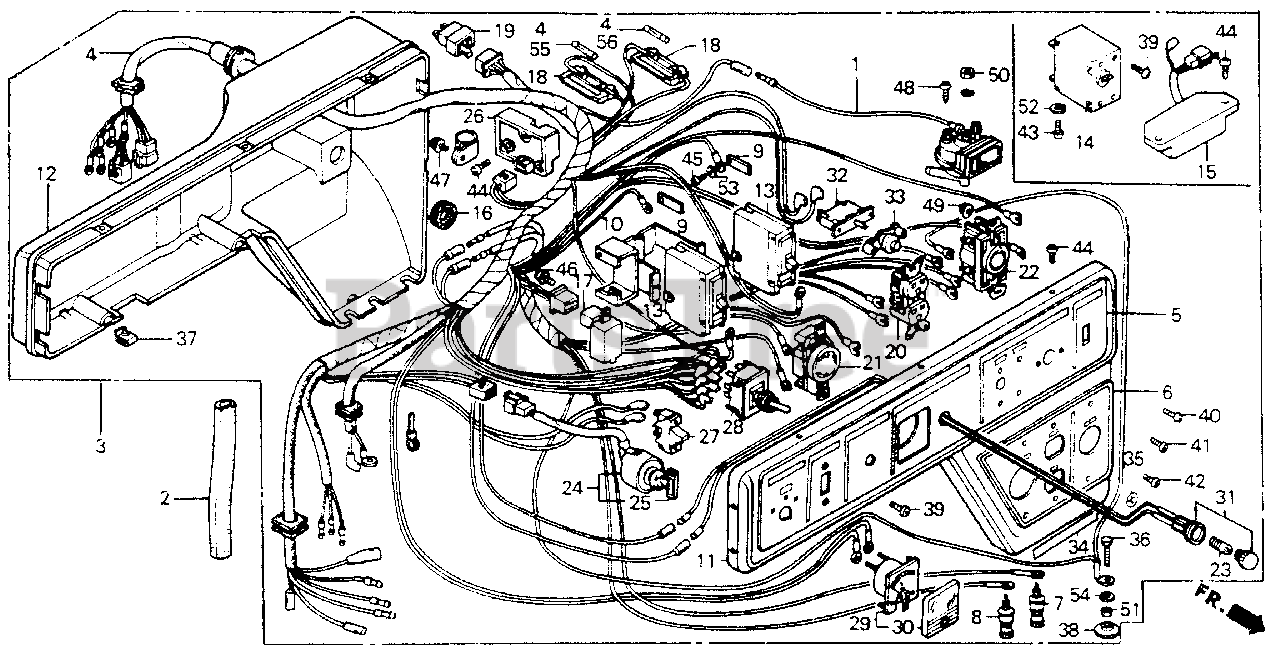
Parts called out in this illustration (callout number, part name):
1	SWITCH ASSY., UNIT
2	TUBE, FASTENER (25) (NOT AVAILABLE)
3	BOX ASSY., CONTROL *R8* (BRIGHT RED)
4	WIRE HARNESS ASSY.
5	MARK, SWITCH PANEL
6	MARK, A.C. OUTPUT
7	TERMINAL, D.C. OUT (+)
8	TERMINAL, D.C. OUT (-)
11	PANEL, CONTROL *R8* (BRIGHT RED)
12	CASE, CONTROL (NOT AVAILABLE)
14	BREAKER, CIRCUIT (19.5A) (NOT AVAILABLE)
15	UNIT, VOLTAGE LIMIT (NOT AVAILABLE)
16	GROMMET, UNIT SWITCH
17	DIODE (NOT AVAILABLE)
18	CASE, FUSE CONNECTOR
19	CONNECTOR ASSY.
20	RECEPTACLE ASSY. (125V-20A)
20	RECEPTACLE (20A/125V)
21	RECEPTACLE (3-PRONG) (30A/125V)
22	RECEPTACLE (20A/125-250V)
23	BULB (24V2W)
24	SWITCH ASSY., COMBINATION (NOT AVAILABLE)
25	KEY
26	CONTROL UNIT, IDLE
27	SWITCH ASSY., IDLE CONTROL (NOT AVAILABLE)
28	SWITCH ASSY., VOLT CHANGE
29	VOLTMETER ASSY.
30	LENS, METER
31	SOCKET ASSY., PILOT LAMP
32	PROTECTOR, CIRCUIT (DC)
33	LENS ASSY., PROTECTOR
34	MARK, D.C. OUTPUT (NOT AVAILABLE)
35	MARK, GROUND
36	BOLT, HEX. (6X18)
37	NUT, SPRING (5MM)
38	NUT, SPECIAL (6MM)
39	SCREW, PAN (3X6)
40	SCREW, PAN (3X12)
42	SCREW, PAN (4X8)
44	SCREW, PAN (5X12)
46	SCREW-WASHER (4X12)
47	SCREW-WASHER (5X10)
48	SCREW, TAPPING (5X10)
49	NUT, HEX. (4MM)
50	NUT, HEX. (5MM)
51	NUT, HEX. (6MM)
54	WASHER, SPRING (6MM)
55	FUSE B (5A)
56	FUSE B (10A)
